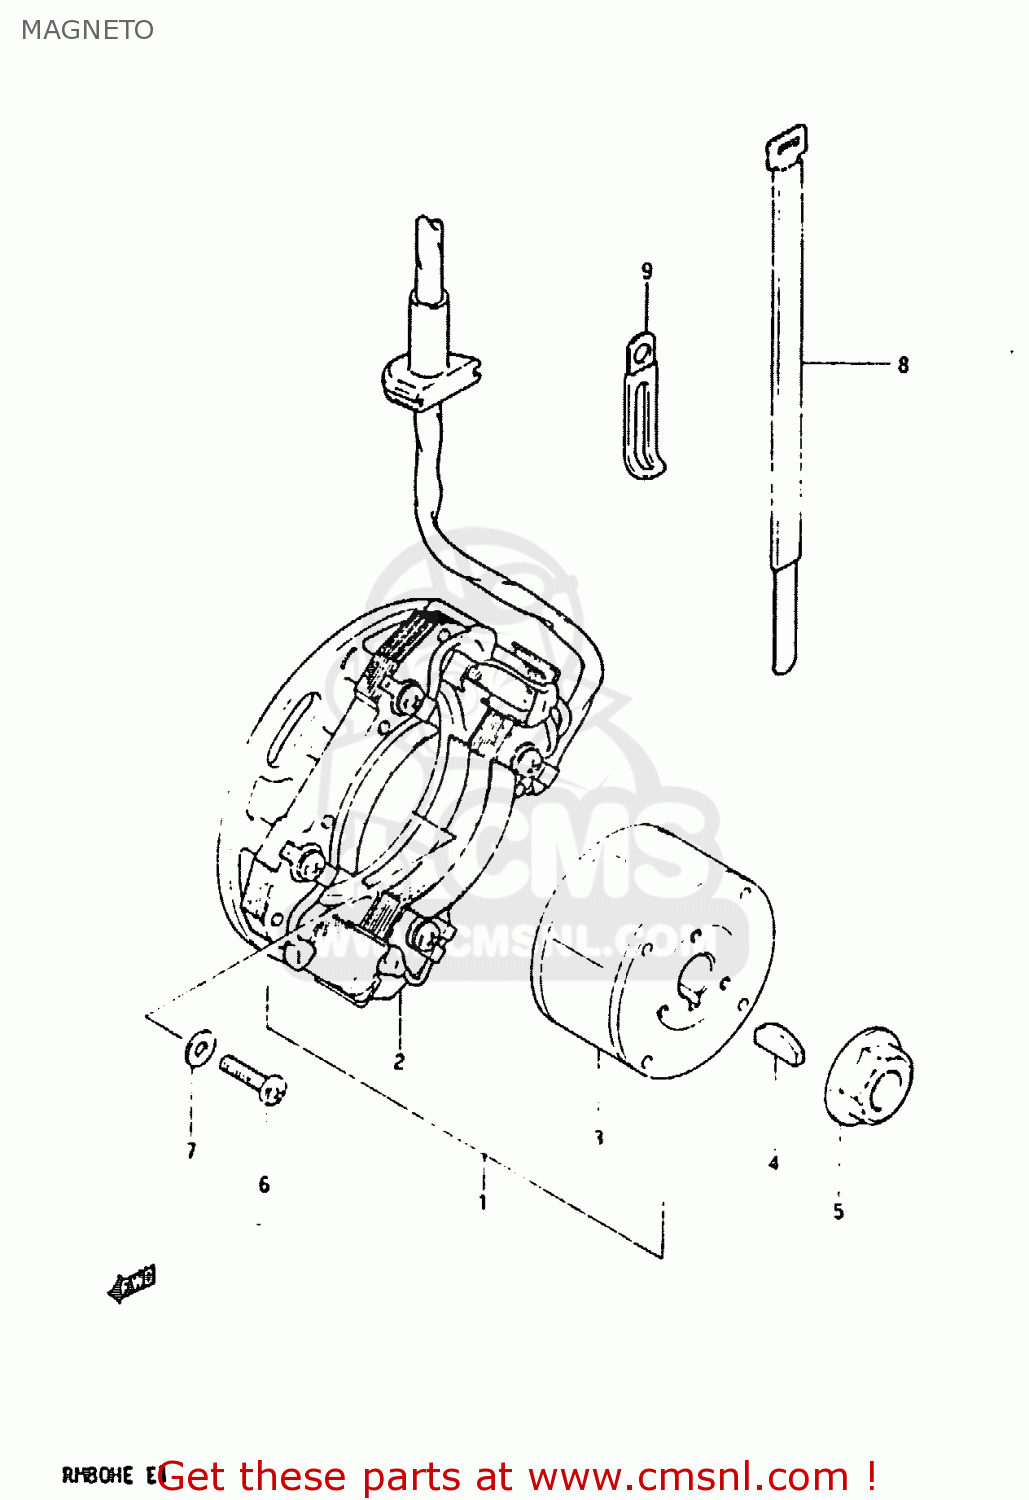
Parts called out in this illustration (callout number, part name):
1	MAGNETO ASSEMBLY
2	STATOR ASSEMBLY
3	ROTOR ASSEMBLY
4	KEY 4MM
5	NUT
6	SCREW
7	WASHER
8	CLAMP(L:250)
9	CLAMP L:35
